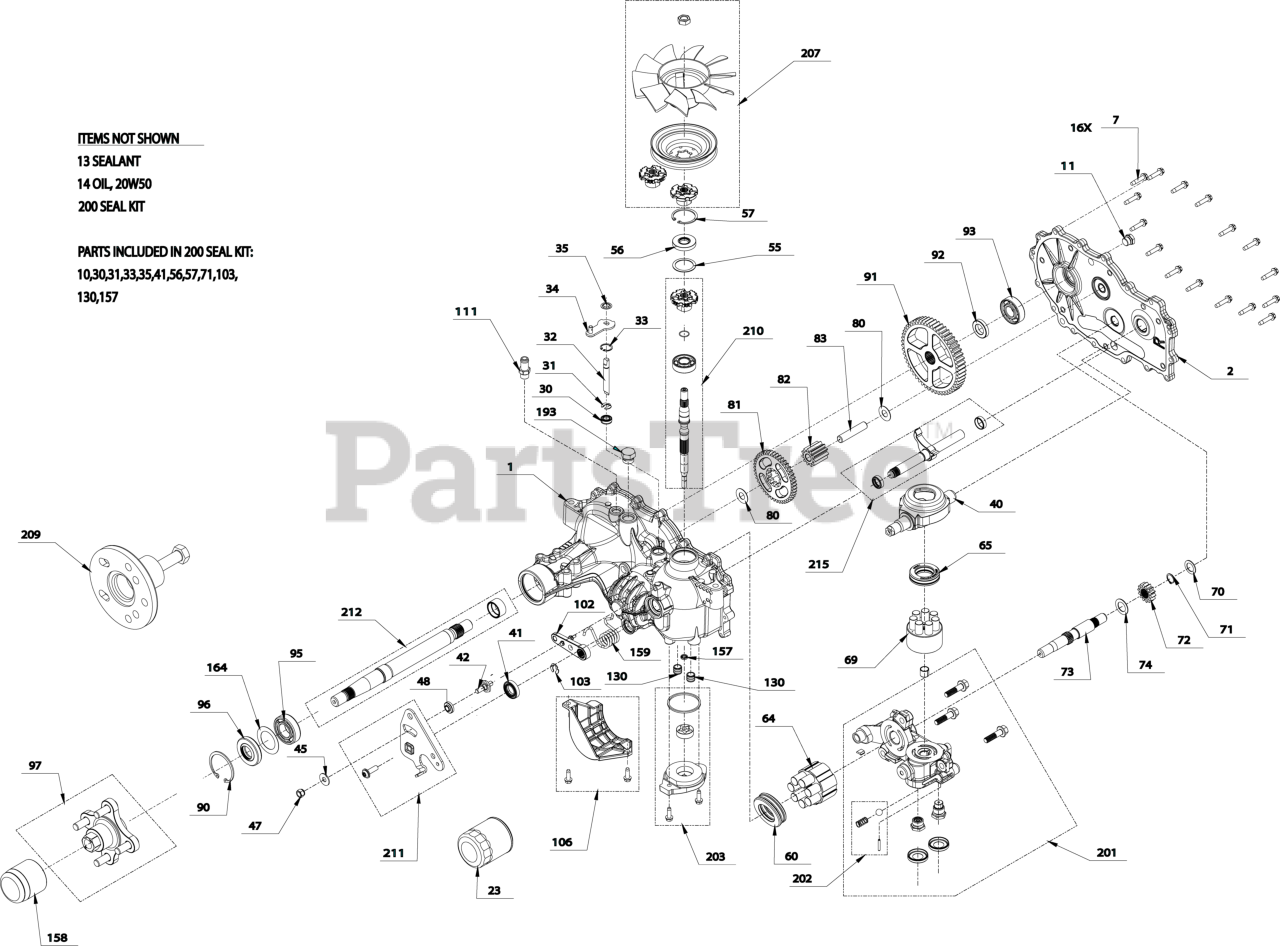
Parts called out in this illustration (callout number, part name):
1	KIT, HOUSING, MAIN, RH, CHRG, CNTL
2	KIT, SIDE COVER, RH
7	SCREW,HEX WASHER 1/4-20X1.125
11	PLUG EXT HEX VENT 9/16 18
13	SEALANT TUBE 10.1OZ.
14	FLUID, HYDRO 15W50 QT
14	FLUID, HYDRO 20W50 QT
23	FILTER, HYDRO-GEAR 2800 TRANS
30	Seal, lip .375 x 375 x 325
31	RING. RETAINING
32	ROD, BYPASS
33	RING, RET .750
34	ARM, BYPASS
35	RING, RTNG .
40	TRUNNION, SWASHPLATE
41	SEAL, LIP 18X32X7
42	STUD. SHORT 5/16-24
47	NUT, HEX 5/16-24 NYLON
48	SPACER
55	WASHER 1.23X1.56X.04
56	SEAL, LIP 17X40X7
57	RING, RET 1.56 INT
60	HG THRUST BEARING (51462)
64	HG 16CC CYLINDER BLOCK (71579)
65	BEARING. THRUST 30 X 52 X 13
69	ASSY, BLOCK 7 PISTON
71	RING, RET 62 EXT
73	SHAFT, MOTOR
74	WASHER .71 X 1.16 X .04
80	WASHER .5X1.0X.032
81	GEAR 45 TOOTH
83	JACK SHAFT (PIN)
90	RING, RETAINING
91	GEAR 54 TOOTH
92	SPACER
93	KIT, BEARING
95	BEARING, BALL 25.4 X 52 X 15
96	SEAL, LIP
97	KIT, HUB 4 BOLT
102	BRAKE ARM HG 71957
103	CLIP,BRAKE ARM HYDROGEAR 52027
106	KIT FILTER GUARD
111	KIT, FITTING 1/2 BEADED 9/16
130	TUBE CHARGE TRIPLE ORING
157	KIT GEROTOR SEAL
158	CAP, AXLE
159	SPRING, TORSION CCW
164	WASHER, 1.355 x 2.035 x .021 FLAT
201	KIT, CENTER SECTION, RH CHARGE
202	KIT CHARGE RELIEF
203	KIT, CHARGE
207	KIT, FAN / PULLEY
209	HUB PULLER 5 BLT
210	KIT INPUT SHAFT
211	KIT, ARM, CONTROL
212	KIT SHAFT AXLE
215	KIT, OUTBOARD, RH ROT A / LH ROT B
